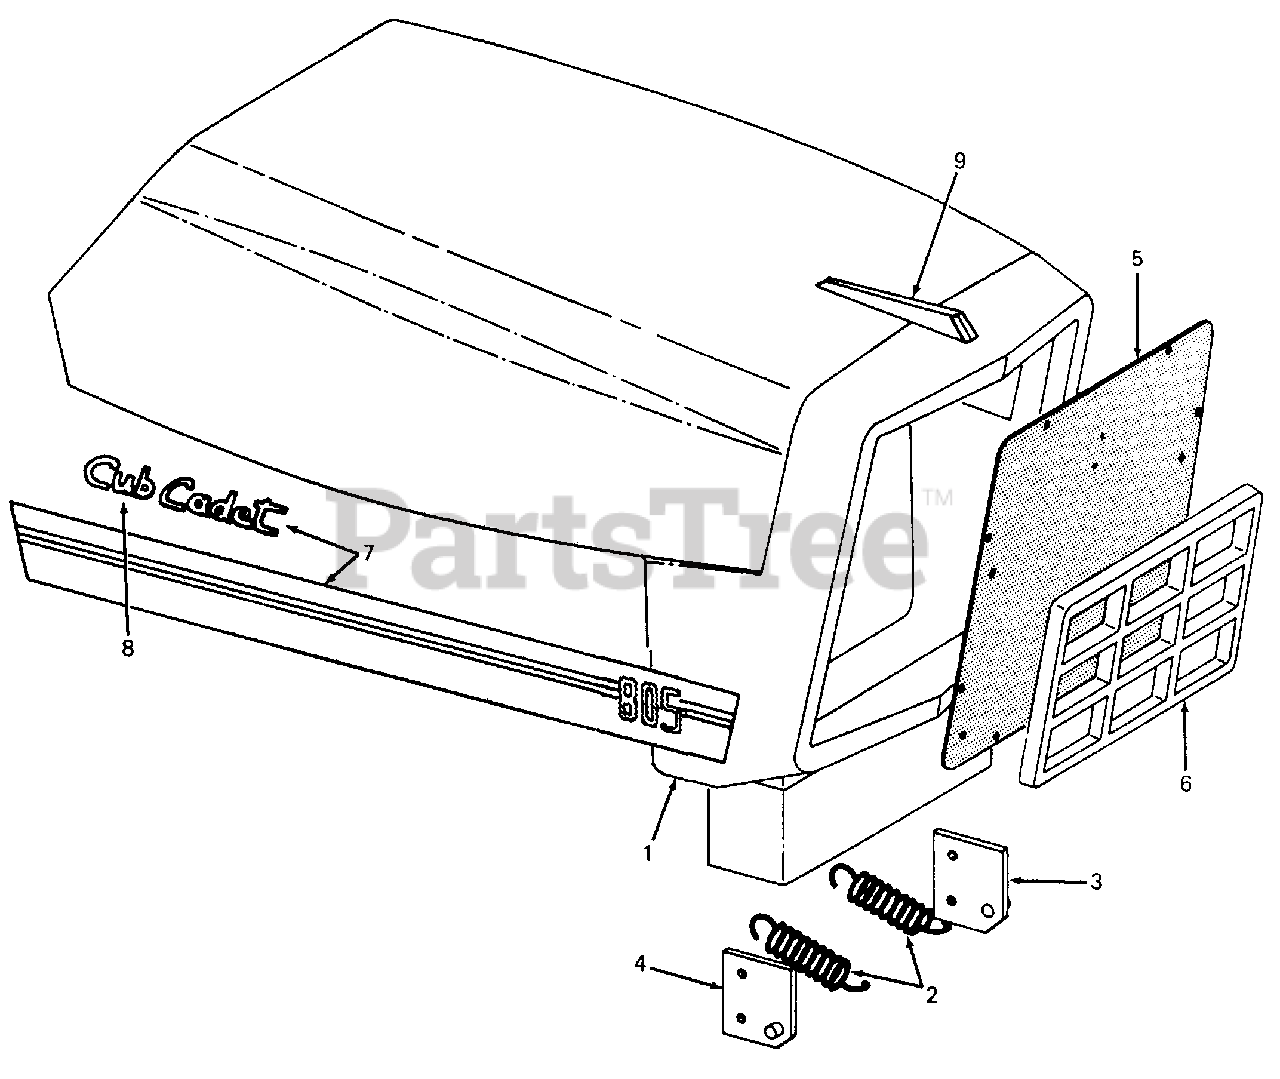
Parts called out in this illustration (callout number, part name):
1	Hood & Grille Assy
2	Spring, Extension
3	Plate, Hood LH
4	Plate, Hood RH
5	Screen, Grille
6	Insert, Grille
7	Graphic, Hood Decal Set
8	Graphic, Cub Cadet Script w/Adhesive
9	Ornament, Hood
